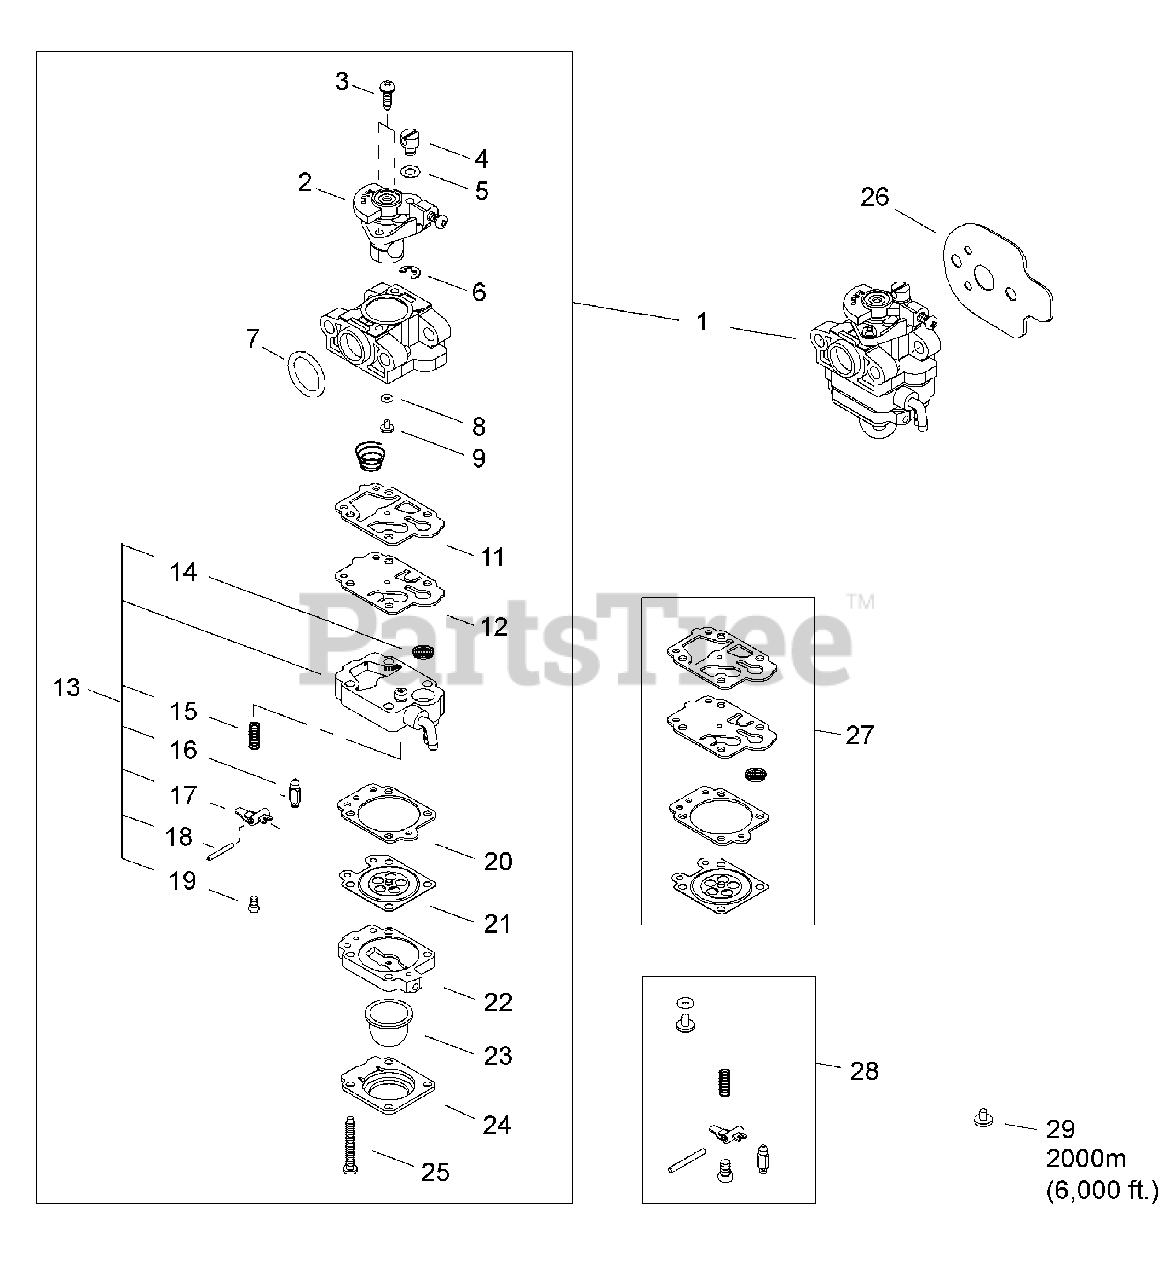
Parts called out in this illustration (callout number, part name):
1	CARBURETOR
2	THROTTLE VALVE ASSY
3	SCREW
4	SWIVEL
5	WASHER
6	RING, RETAINING
7	O-RING - 15
8	O-RING
9	JET, MAIN
11	GASKET, PUMP
12	DIAPHRAGM, PUMP
13	PUMP BODY ASSY
14	STRAINER
15	SPRING, METERING LEVER
16	VALVE, INLET NEEDLE
17	LEVER, METERING
18	PIN, METERING LEVER
19	SCREW, METERING LEVER PIN
20	GASKET, METERING
21	DIAPHRAGM, METERING
22	BASE, PURGE
23	BULB, PURGE
24	RETAINER, PURGE BULB
25	SCREW, PUMP COVER
26	GASKET
27	DIAPHRAGM/GASKET KIT
28	INLET NEEDLE VALVE KIT
29	JET, MAIN - 2000M
